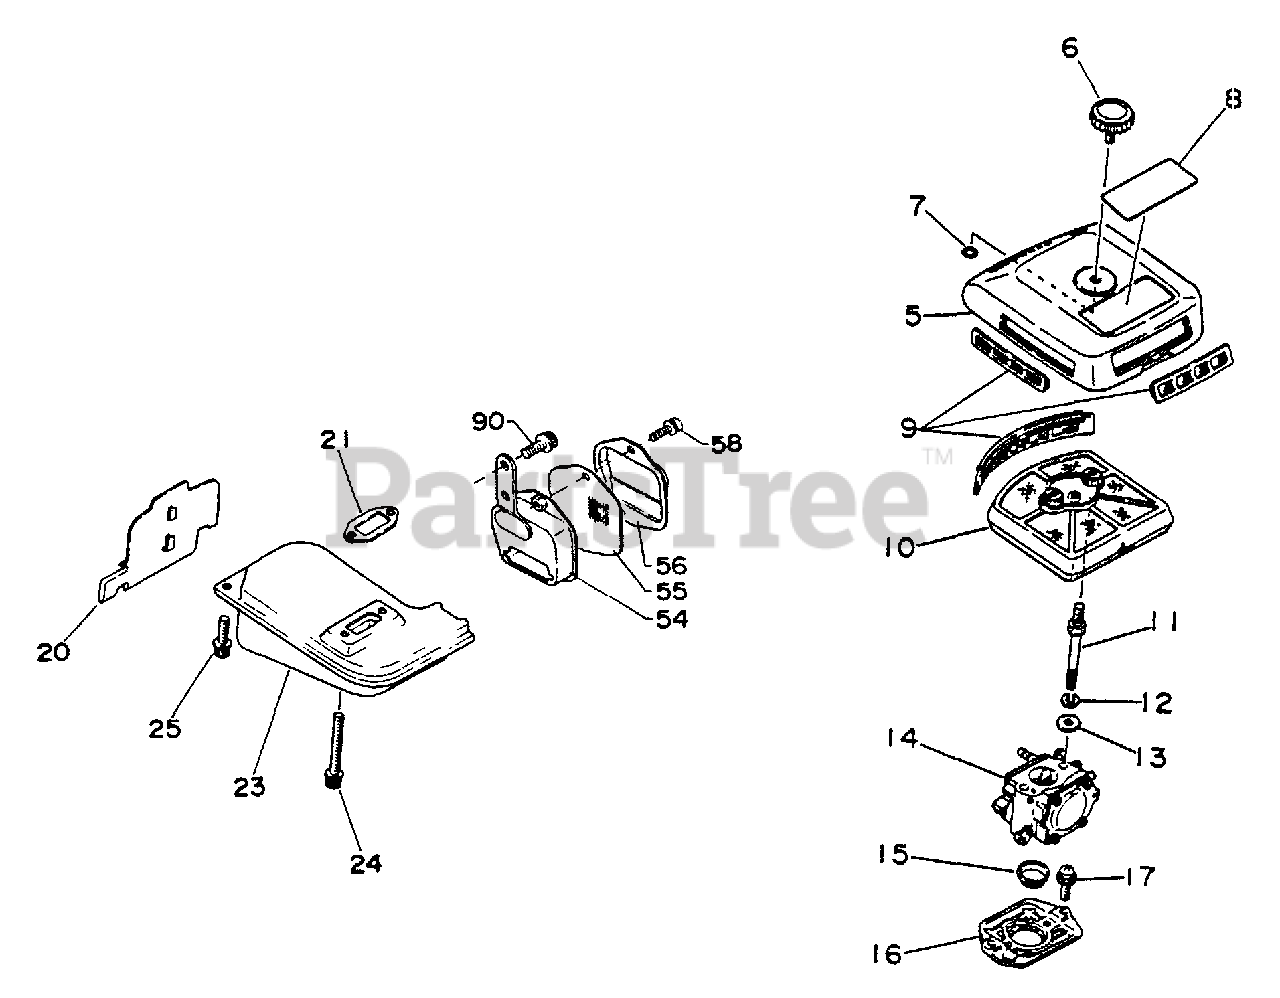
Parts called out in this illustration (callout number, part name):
5	COVER, AIR FILTER
6	THUMBSCREW
7	O-RING 3
8	LABEL
9	DEBRIS FILTER KIT
10	FILTER, AIR
11	SCREW
12	WASHER, SPRING 5
13	WASHER
14	CARBURETOR
15	HOLDER
16	ADAPTER
17	SCREW 4×12
20	INSULATOR
21	GASKET, EXHAUST
23	MUFFLER
24	BOLT 5×50
25	BOLT 5×20
54	ADAPTER
55	SCREEN, SPARK ARRESTER
56	GUIDE, EXHAUST
58	SCREW 4×12
90	BOLT 5×12
